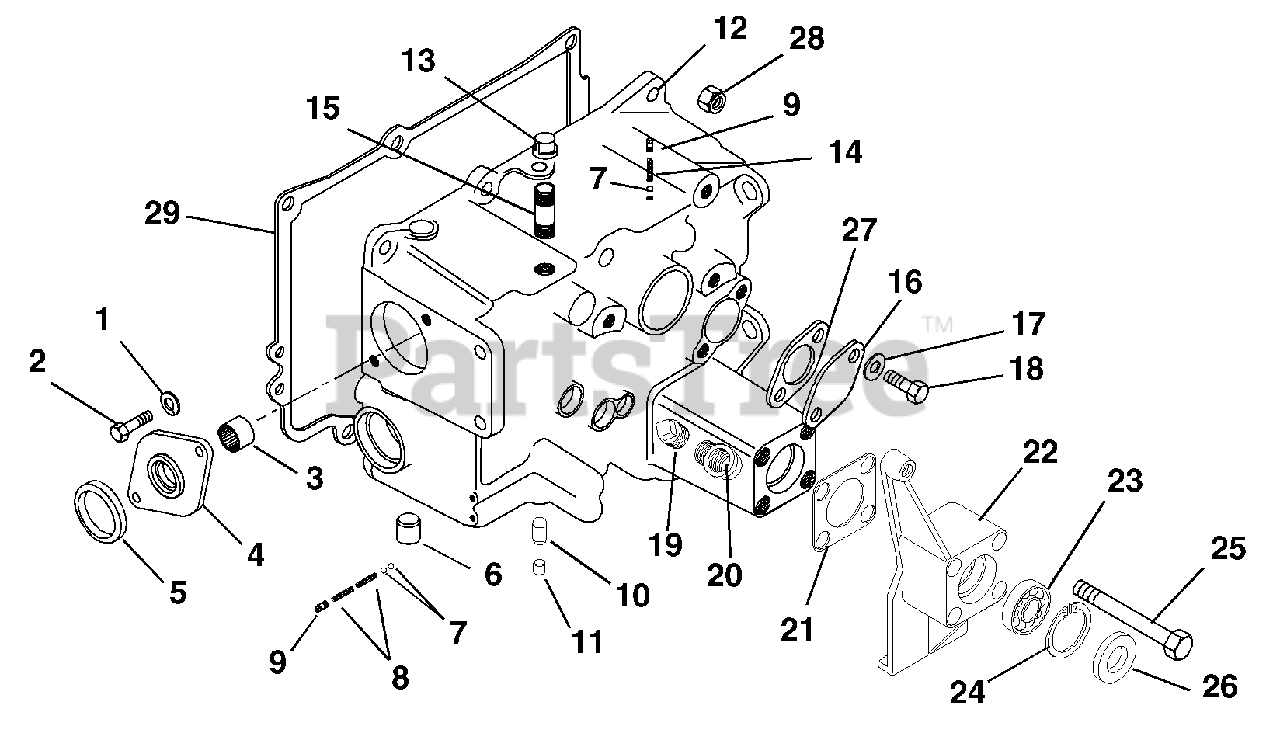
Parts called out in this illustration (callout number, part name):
1	Washer-Locking .31 x .078
2	Bolt-Hex .31-18 x 1.00 Grade 5
3	Bearing-Needle .75 x 1.00 x .50
4	Cap, Front PTO
5	Seal .75 x 1.25 x .136
6	Plug, Cup .50
7	Ball .31
8	Spring-Compression .045 x .30 x 1.50
9	Plug-Pipe .12 Square Head Unfinished Steel
10	Pin, Interlock
11	Plug, Cup .38
12	Assembly, Transmission Case
13	Cap, Pipe .50 NPT
14	Spring-Compression .045 x .30 x .94
15	Nipple, Pipe .50 x 2.50 Unfinished Steel
16	Plate, Cover
17	Washer-Flat-Steel .41 x .81 x .065
18	Bolt-Hex .38-16 x .75 Grade 5
19	Plug-Pipe .50 Square Head Unfinished Steel
20	Elbow .50 x 90 Straight Unfinished
21	Gasket
22	Retainer, Axle Bearing
23	Bearing Ball 1.25 x 2.25 x .50
24	Ring-Retaining-External 2.49 x .078
25	Bolt-Hex .50-13 x 3.25 Grade 5
26	Seal 1.25 x 2.25 x .50
27	Gasket, Cover Plate
28	Nut-Locking-Center .38-16
29	Gasket-Transmission Cover
